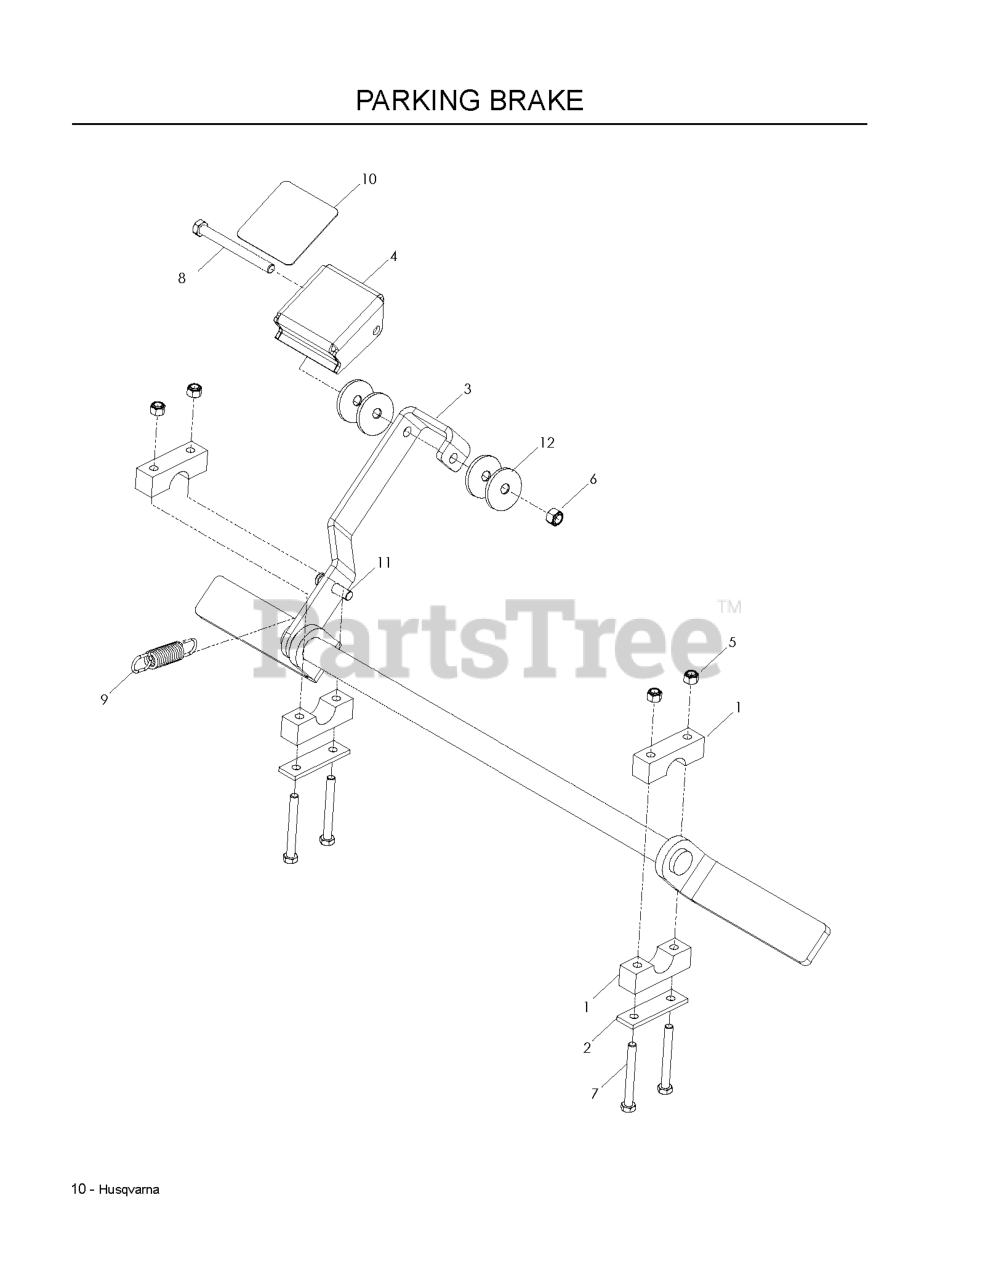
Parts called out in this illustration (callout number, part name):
1	PILLOW BLOCK
2	REINFORCEMENT BAR
4	PEDAL, BLACK
5	NUT 5/16 NYLOC
6	NUT 3/8-16 NYLOC
7	HCS 5/16C X 2-3/4
8	HCS3/8-16.X
9	SPRING, EXTENSION
10	ANTI-SKID PAD
11	CLEVIS PIN, 3/8 X 1 1/2
12	WASHER, FRICTION
